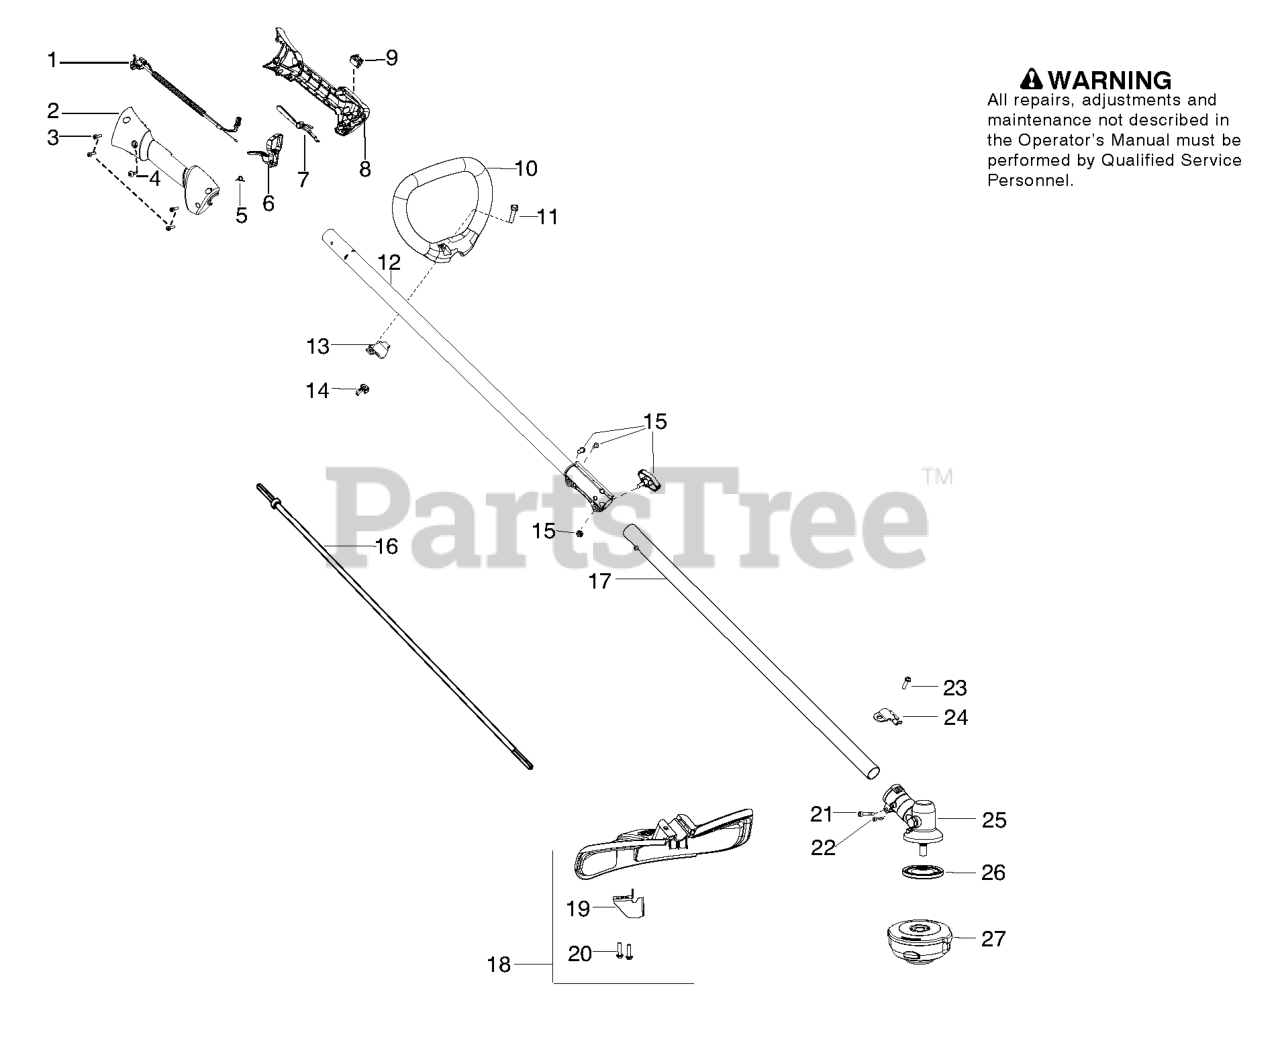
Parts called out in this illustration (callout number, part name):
1	Assy - Cable/Wire Harness
2	Housing - Throttle (RH)
3	Screw
4	Screw
5	SPRING TRIGGER
6	Trigger
7	Lockout - Throttle
8	Housing - Throttle (LH)
9	Kit - Switch
11	BOLT, TYPE 2
12	KIT UPPER SHAFT SILVER
13	CLAMP ASSIST HANDLE
14	WINGNUT, TYPE 2
15	ASSY COUPLER BLACK
17	KIT LOWER SHAFT
18	KIT COBI SHIELD
19	Limiter - Line
21	SCREW - CARB. ADAPTOR
23	SCREW 1/4-20 X 7/8 (TAP
24	BRACKET SHIELD STRAIGHT SHAFT
25	ASSY GEARBOX
26	DRIVE DISC
27	T25 TRIM HEAD 10MM LH
